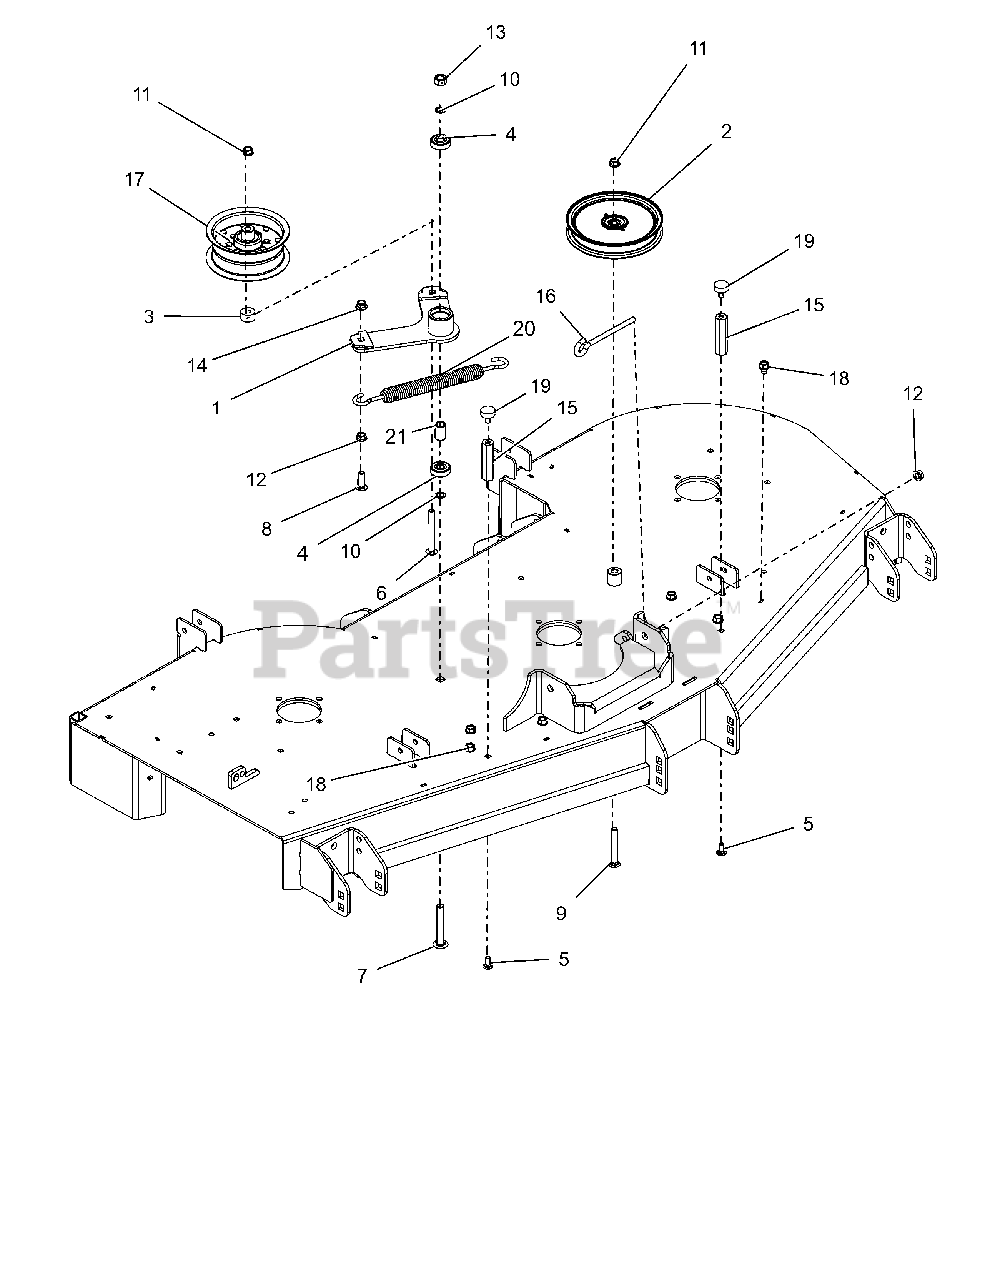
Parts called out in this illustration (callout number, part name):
1	WLDMT, DECK IDLER ARM
2	IDLER, FLAT-6.00" X .75"
3	SPACER .390X1.000X.562
4	BRG-BALL .500X1.38X.437
5	BLT,RDHDSQNK .31-18X.75 LOCTIT
6	@BLT-RHDSSQNK .38-16X3.50 G5YZ
7	BLT,RDHDSQSHNK.50-13X3.25 G5YZ
8	@BLT-RHDSSQNK .38-16X1.25 G5YZ
9	@BLT-RDHDSQNK .38-16X3.00 G5YZ
10	WASHER, .500X.750X.020 THRUST
11	NUT-LK-CTR-FLG .38-16 YWZC
12	@NUT-SPNLK-FLG .375-16 YWZC
13	@NUT-LK-CTR .50-13 YWZC
14	@NUT-LK-NYL-FLG .38-16 YWZC
15	NUT, COUPLING .31-18 X 3.00
16	BOLT,.38-16 X 4.25-.62 DIA EYE
17	PULLEY, FLAT 5.00X2.36X.375
18	@SCR-TAP .38-16X.50 HWH TR YWZ
19	BUMPER, RUBBER
20	SPRING, EXTENSION
21	SPACER .510 X .75 X 1.1485
